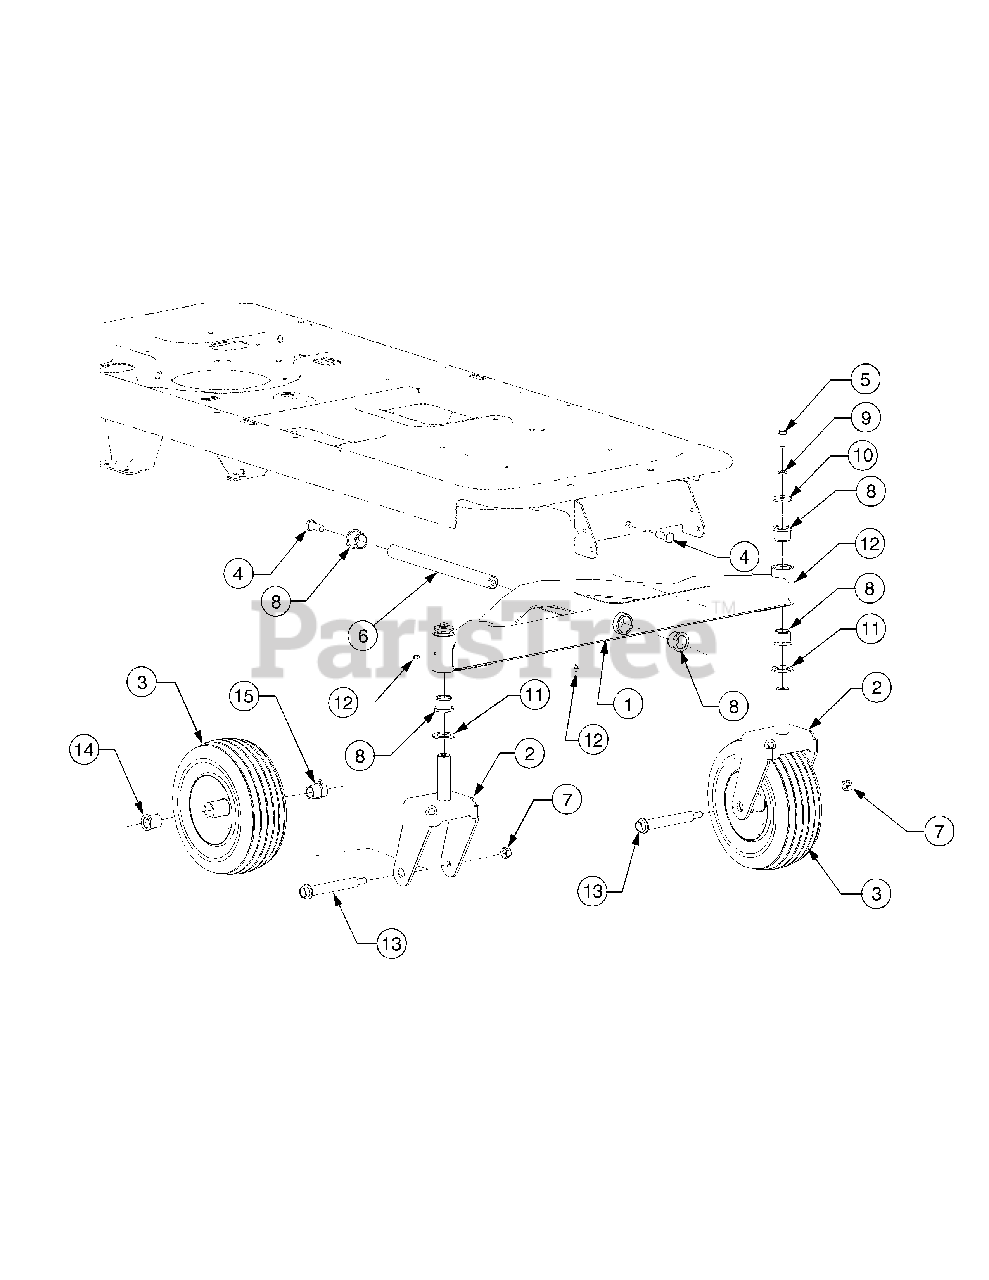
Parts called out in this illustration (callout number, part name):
2	Caster Wheel Bracket
3	Wheel Ass’y 11 .0 x 4.0 x 5.0 Grey
4	Hex Lock Screw 1/2-13 x 1.25 Gr. 5
5	Hex Screw 3/16 x 1.00
7	Hex Cent. L-Nut 1/2-13 Thd. (Gr. 5)
8	Flange Bearing 1.0 x 1,246
9	L-Wash 3/8 ID
10	Flat Washer .39 ID x 1.5 OD x .135
12	Grease Fitting
13	Shoulder Screw .75 x 4.75:7/16-14
14	Flange Brg. .75" ID
15	Flange Brg. .76 ID w/Lube Ftg.
